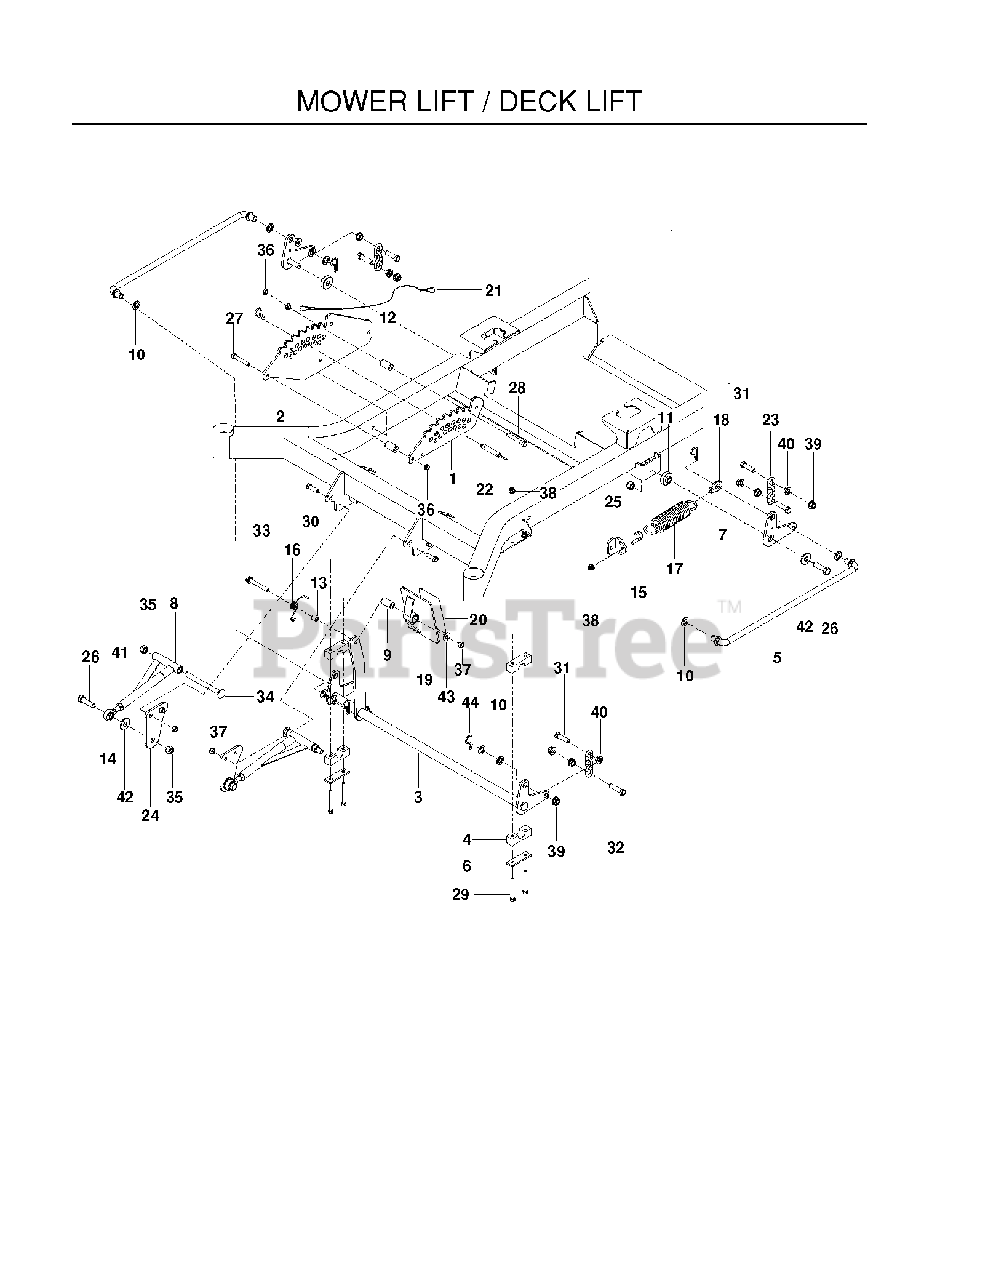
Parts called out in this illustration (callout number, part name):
1	PLATE, HEIGHT, BLUE
2	PLATE, HEIGHT, MAIN, BLUE
3	SHAFT, LIFT, DECK
4	PILLOW BLOCK
5	CROSS LINK
6	REINFORCEMENT BAR
7	BELLCRANK, REAR LIFT
8	STRUT, DECK, BLK
9	BUSHING, SLEEVE
10	BUSHING
11	IDLER SPACER
12	DECK LIFT SPACER
14	ROD END
16	SPRING, TORSION
18	TAB, SPRING
19	PEDAL, FOOT, WELDMENT
20	FOOT PAD
21	LANYARD
22	HITCH PIN
23	LIFT CHAIN - 3 LINK
24	MOUNT, STRUT
25	MOUNT, SPRING
26	HCS 1/2-13 X 1 3/4 GR 8
27	HCS 3/8C X 2 1/4
28	HCS 3/8C X 2 1/2
29	HCS 5/16C X 2-3/4
30	HCS 3/8C X 1 1/4
31	HCS 7/16C X 1 1/2
32	HCS 7/16 - 14 X 1 3/4
33	HHFS 3/8-16 X 2 3/4
34	1/2-13X5-1/2 CAR BLT
35	NUT 1/2-13 HEX NYLOC ZD
36	NUT HEX 3/8-16 NYLON, THIN
37	NUT 3/8-16 NYLOC
38	5/16-18 NYLOC FLANGE NUT
39	NUT 7/16-14 HEX WHIZ LK
40	NUT 7/16C WHIZ
41	NUT 1/2-20 HEX JAM ZD
42	WASH USS FLAT 1/2
43	WASHER 3/8 FLAT
44	PIN, COTTER 1 3/4
